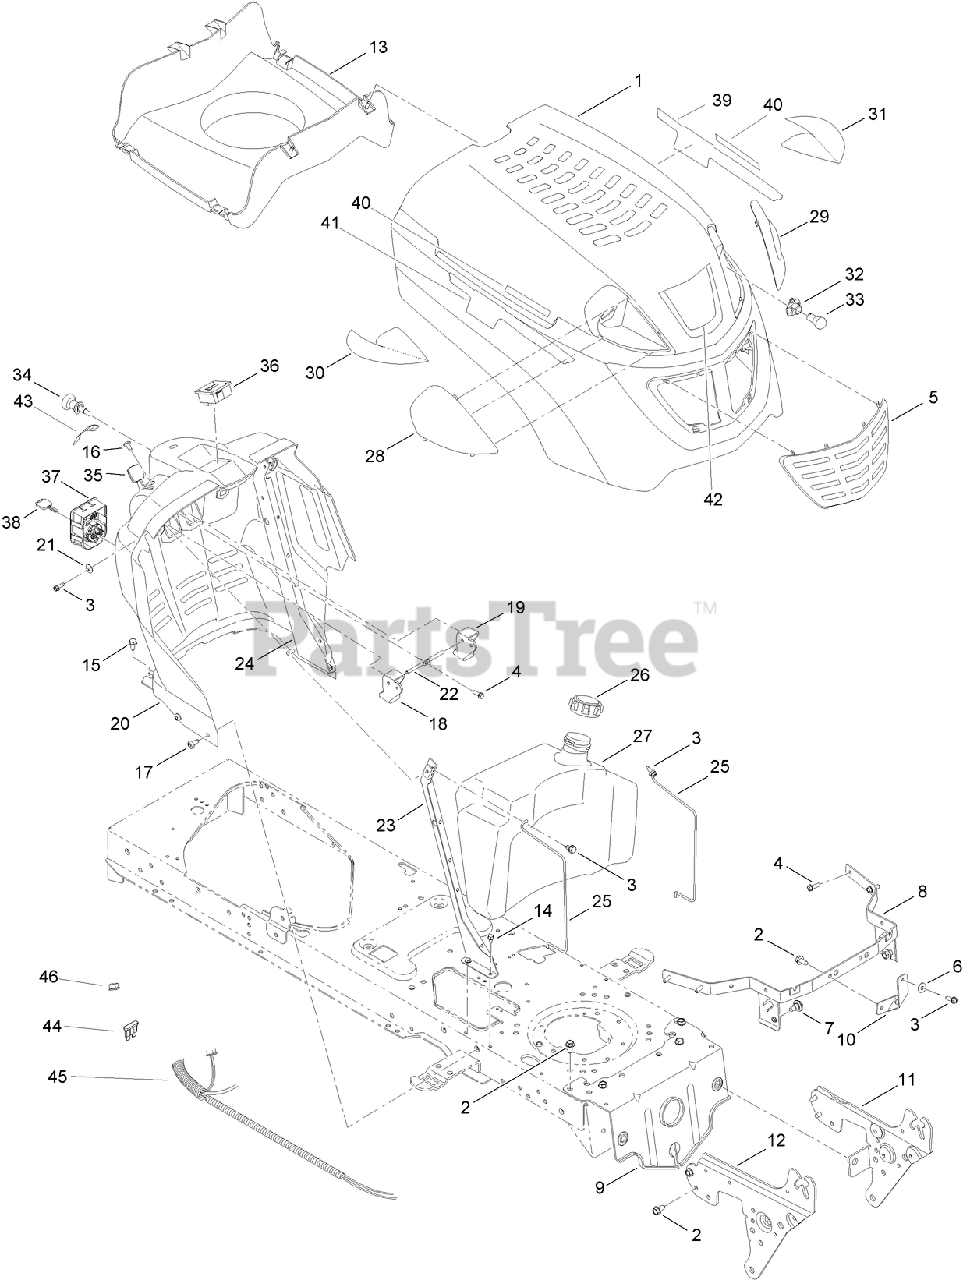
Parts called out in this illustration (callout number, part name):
2	SCREW-TAP
3	SCREW-TAP
4	SCREW-TAP
6	WASHER-FLAT
7	BOLT-SHOULDER, TAP
8	BRACKET-PIVOT
9	BRACKET-PIVOT
10	BRACKET-SUPPORT, HOOD
11	BRACKET-PIVOT, SUPPORT (LH)
12	BRACKET-PIVOT, SUPPORT (RH)
13	PLENUM-HOOD
14	SCREW-HWHTF
15	SCREW-TAP
16	SCREW-TAP
17	SCREW-TAP
18	LEVER-CRUISE
19	LEVER-BRAKE
20	DASH-PTO, ELECTRIC
21	WASHER-SPRING
22	ROD-LEVER, BENT
23	SUPPORT-DASH, RH
24	SUPPORT-DASH, LH
25	ROD-SUPPORT
26	CAP-FUEL
27	TANK-FUEL, 3 GAL
28	LENS-RH
29	LENS-LH
30	REFLECTOR-RH
31	REFLECTOR-LH
32	SOCKET-HEADLIGHT
33	LAMP-12V, MINIATURE
34	CABLE CONTROL ASM (W/CHOKE KNOB)
35	CABLE-THROTTLE
36	METER-HOUR
37	MODULE-SWITCH, IGNITION
38	KEY-IGNITION
39	DECAL-SIDE PANEL, LEFT
40	DECAL-SIDE PANEL
41	DECAL-SIDE PANEL, RIGHT
42	DECAL-HOOD
43	DECAL-THROTTLE, DASH
44	FUSE-20 AMP
45	WIRE-HARNESS
